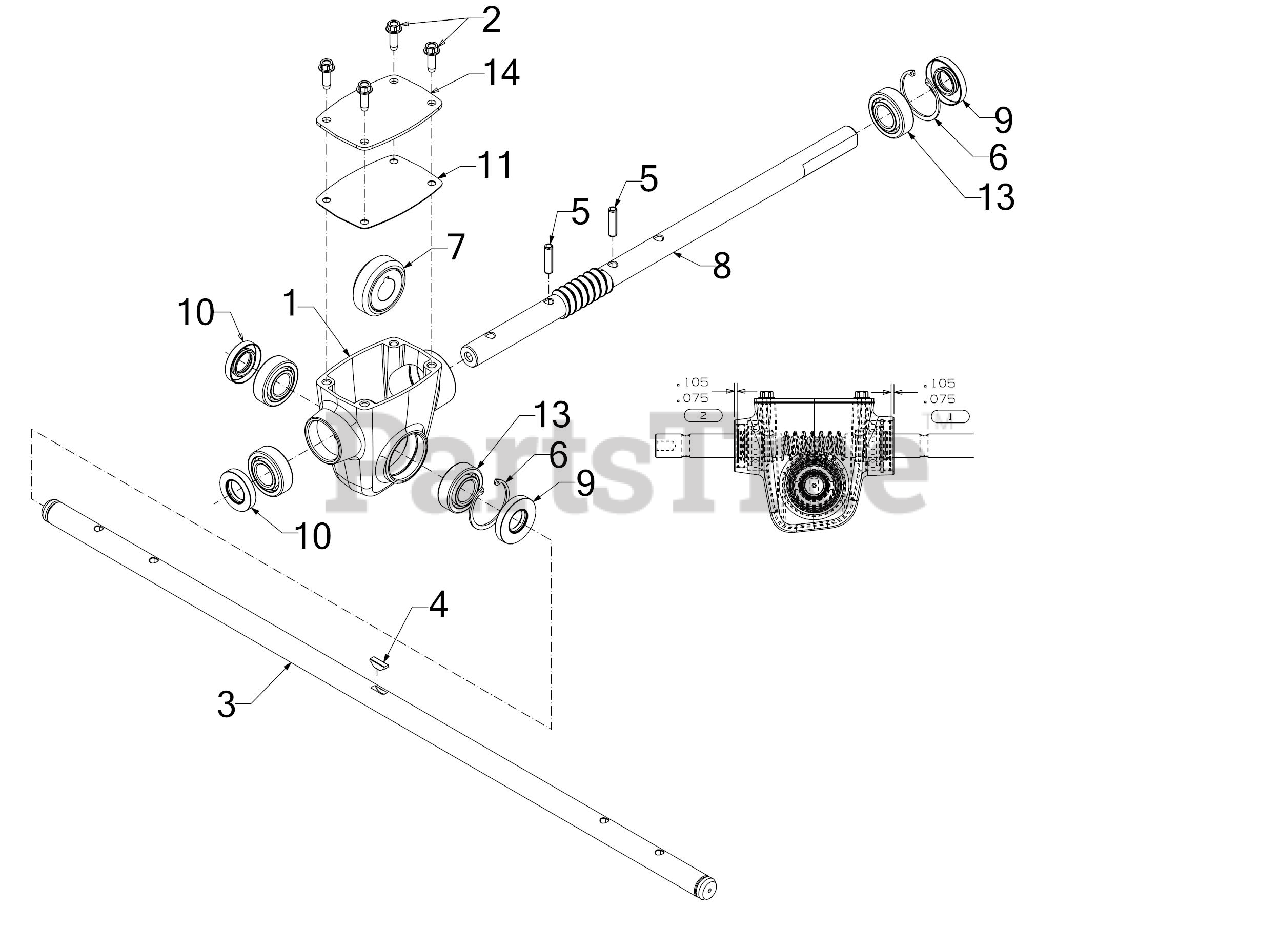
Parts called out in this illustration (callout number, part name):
1	AUGER GEARBOX HOUSING
2	SCREW 1/4-20 x .750
3	30" AUGER AXLE
4	KEY 3/16 x 5/8 H
7	WORM GEAR 20T
11	GEARBOX COVER GASKET
13	BALL BEARING
14	GEARBOX COVER
